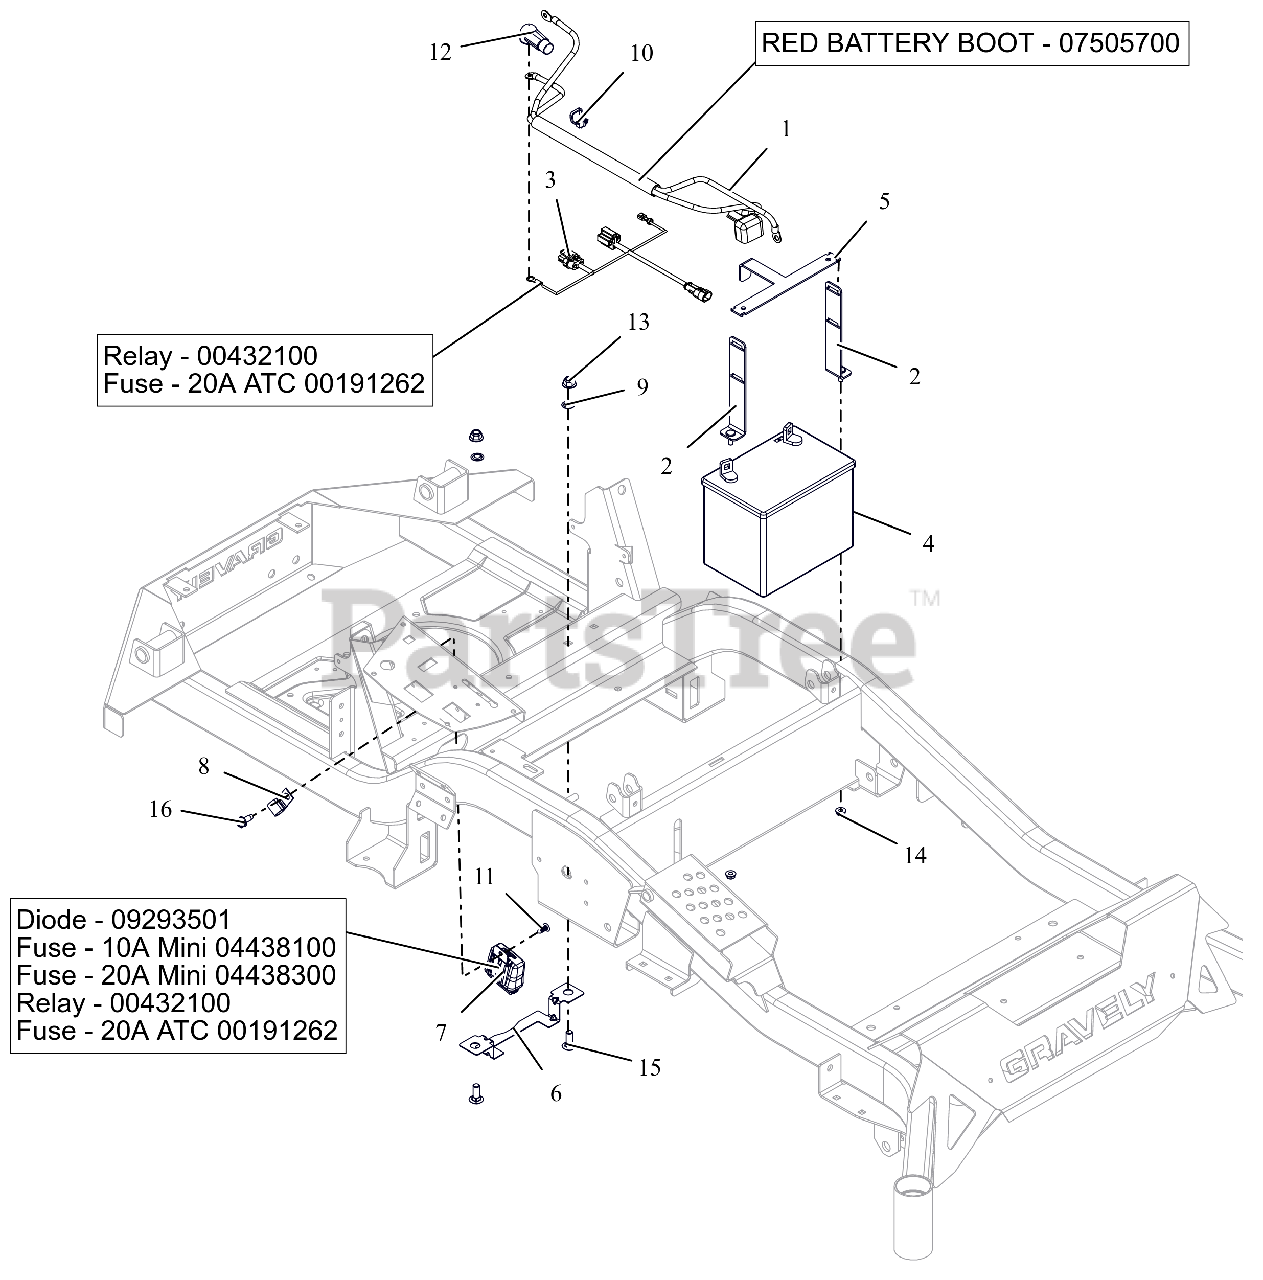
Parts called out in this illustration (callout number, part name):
1	HARNESS, BATTERY HD
1	INSULATOR
2	WMT,BATTERY MOUNT HOLD DOWN
3	HARNESS, STARTER ADAPTER
3	RELAY,SEALED W/DIODE
3	FUSE, 20 AMP BLADE S/O
4	BATTERY, 300 CCA 10U1L
5	BRKT, BATTERY TIE DOWN
6	GUARD, ELECTRICAL HARNESS
7	HARNESS, WIRE
7	DIODE, CONNECTOR SHELL
7	FUSE,10 AMP MINI-ATC
7	FUSE,20 AMP MINI ATC
7	RELAY,SEALED W/DIODE
7	FUSE, 20 AMP BLADE S/O
9	NUT-PUSH .38 DIA. PAL ZINC
10	CABLE TIE W/ TREE (.25 HOLE)
11	RIVET, .25 NYLON PANEL
12	BOOT, .65ID POS
13	NUT,NYL-FLG .38-16 GF ZCC
14	NUT-LK-TOP-FLG .250-20 GF ZCC
15	BLT, RHSN .38-16X1.00 G5 ZCC
16	SCR,TAP .312-18X.75 HWH TR ZCC
